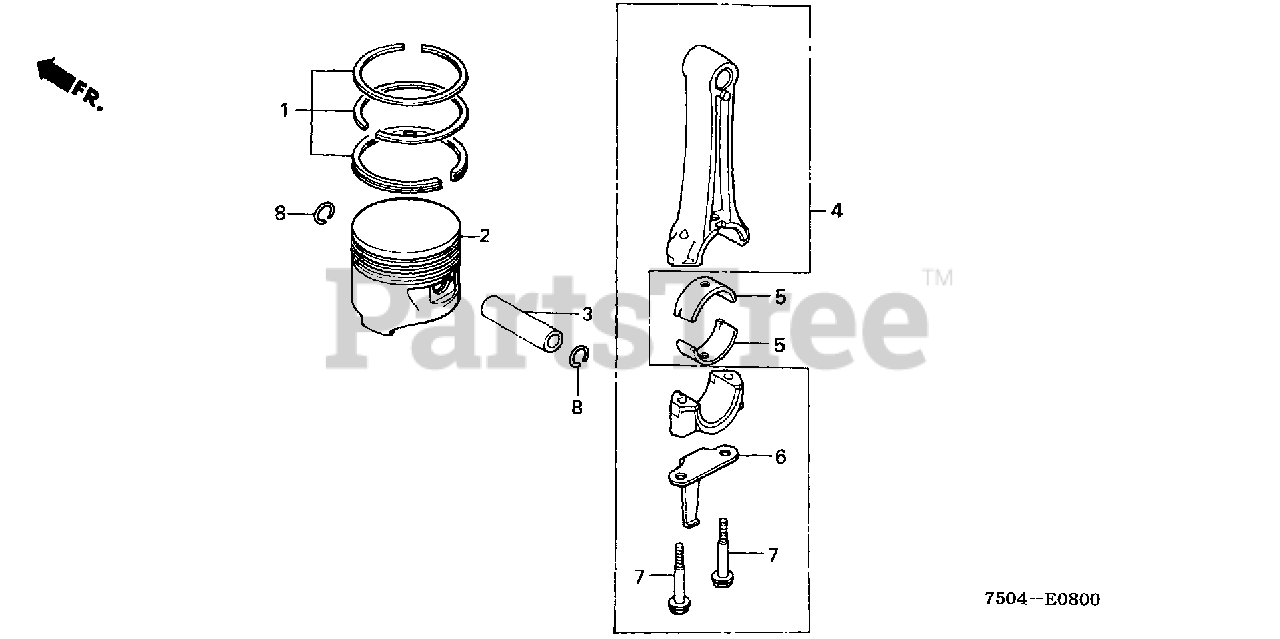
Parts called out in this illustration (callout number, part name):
1	RING SET, PISTON (STD)
1	RING SET, PISTON (STD) (NOT AVAILABLE)
1	RING SET, PISTON (OS 0.25)
1	RING, PISTON (OS 0.50)
1	RING SET, PISTON (OS 0.50)
1	RING SET, PISTON (0.75)
2	PISTON (STD)
2	PISTON (OS 0.25)
2	PISTON (OS 0.50)
2	PISTON (0.75)
3	PIN, PISTON
4	ROD ASSY., CONNECTING
5	BEARING A, CONNECTING ROD (BLACK)
5	BEARING B, CONNECTING ROD (BROWN)
5	BEARING C, CONNECTING ROD (GREEN)
5	BEARING D, CONNECTING ROD (YELLOW)
5	BEARING E, CONNECTING ROD (PINK)
5	BEARING A, CONNECTING ROD
5	BEARING B, CONNECTING ROD
5	BEARING C, CONNECTING ROD
6	DIPPER, CONNECTING ROD
7	BOLT, CONNECTING ROD (8MM)
8	CLIP, PISTON PIN (19MM)
